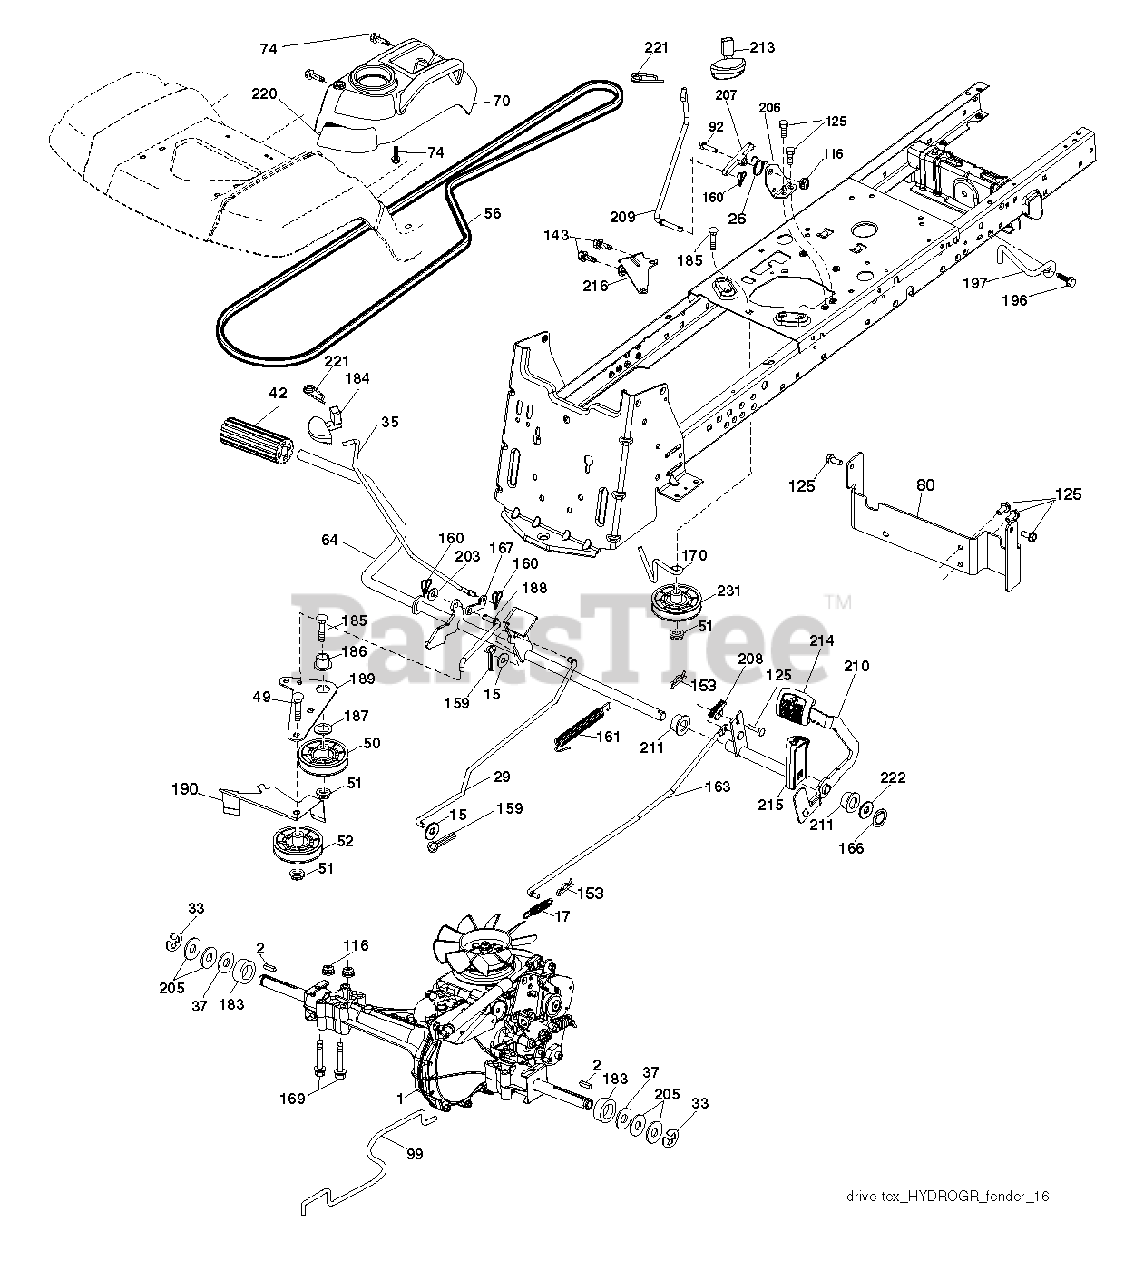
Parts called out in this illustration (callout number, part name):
2	SQUARE KEY
15	WASHER
17	SPRING.BRAKE.K46.GREEN
26	SPRING.RETURN.CRUISE
29	ROD.BRAKE.K46
35	ROD .BRAKE. PARKING. GT. HUSQ.
42	PEDAL COVER T
50	IDLER.FLAT.910.OFFSET
51	NUT LOCK FLG 3/8-16 UNC
52	IDLER.V-GROOVE.910.OFFSET
56	V-BELT.MOWER.92.40.42/K46
64	SHAFT.ASM.PEDAL.BRK.CNTR
70	RP CONSOLE.ASM.PCH.W/TB
74	CONSOLE.ASM.RH.GT.FC.HUSQ
80	Strap Torque
92	BOLT
99	ROD.ASM.BYPASS.0610.FE
116	NUT LOCK HEX FLANGE 5/16-18
125	SCREW
143	SCREW LT
153	RETAINER M
159	COTTER PIN
160	RETAINER CLIP
161	SPRING, RETURN LT
163	ROD.CONTROL.PEDAL.K46
166	NUT.PUSH.625
167	LATCH.BRAKE.SPRING
169	BOLT.HEX.FLNG.5/16-18X3.75
170	KEEPER.CENTER SPAN.1.688
183	SPACER AXLE
184	RB HANDLE.PARKG.BRK.HUS/PRED
186	SPACER.RETAINER
187	WASHER 12/32X2X10GA
188	RP LINK.CLUTCH.GROUND.DRIVE
189	BELLCRANK.GROUND.DRIVE.TEX.
190	KEEPER.BELLCRANK.DRIVE
196	SCREW 3/8-16X1
197	LINK.CLUTCH.ANIT-ROTAT
203	WASHER
206	BRACKET.MOUNT.CRUISE.LATCH
207	LATCH.CONTROL.CRUISE
208	GEAR.SECTOR.CONTROL.CR
209	ROD.CONTROL.CRUISE.GT.
210	ROCKER.ASM.PEDAL.CONTR
211	BEARING.NYLON
213	KNOB.CONTROL.CRUSIE.HU
214	PEDAL.FORWARD.PAD.TEX
215	PEDAL.REVERSE.TEX.GT.4
216	BRACKET.PULLEY.IDLER.W/TEX
220	REFLECTOR.RH.TEX GT
221	RETAINER.SPRING.CLIP.H
222	WASHER 21/32 X 1-1/4 X 10 GA.
231	IDLER.V-GROOVE.1.688.OFFSET
